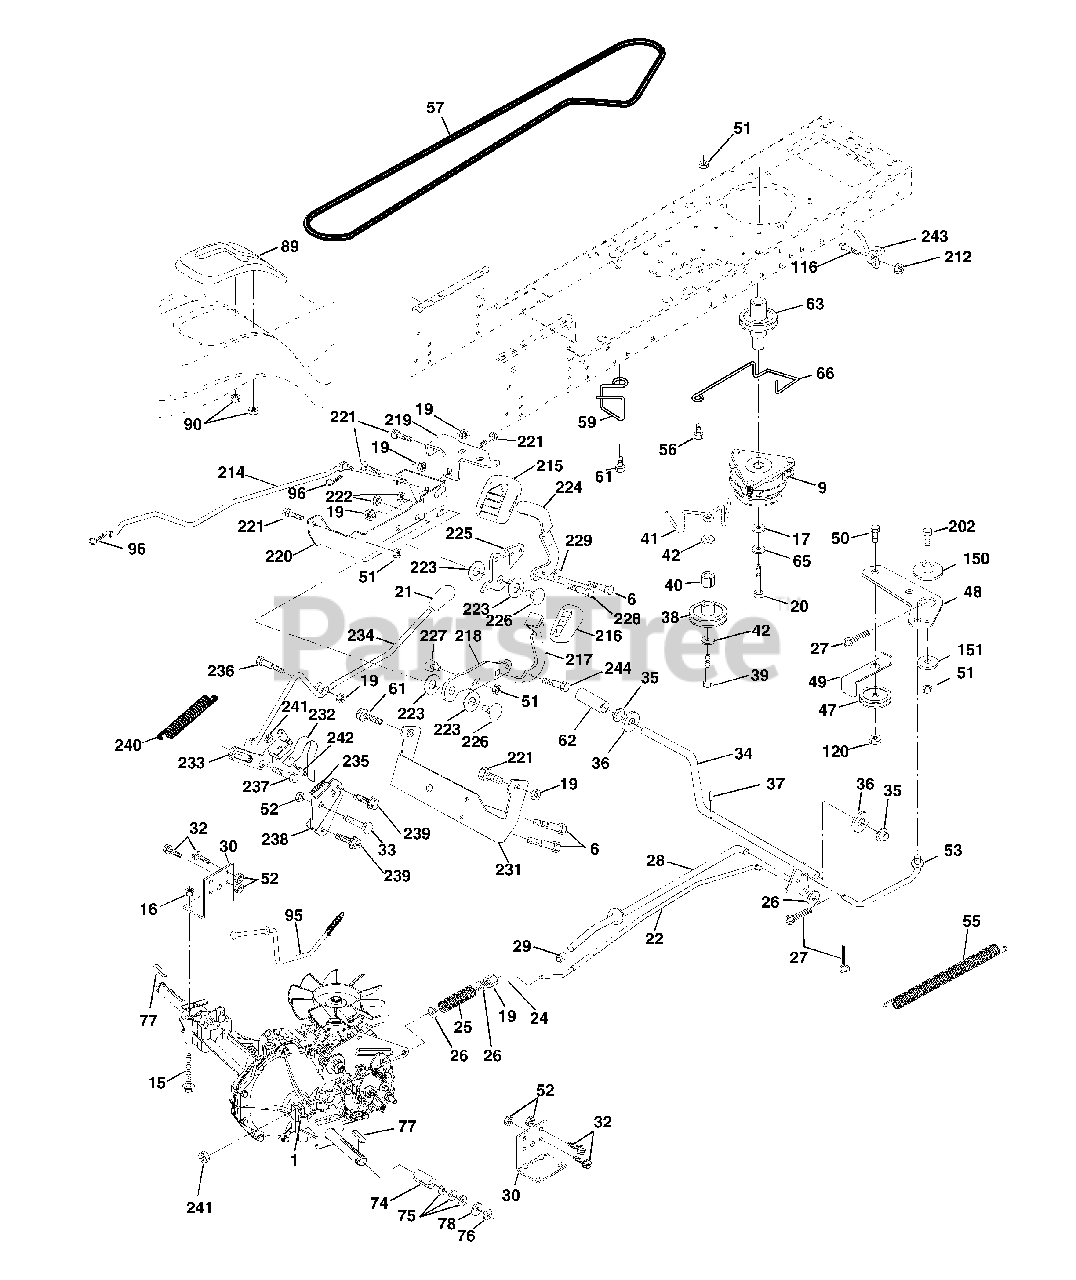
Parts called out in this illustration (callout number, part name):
1	Transaxle
9	Clutch Elec
15	Bolt Hex Flghd 5/16-18 Gr. 5
16	Nut Lock Hex W/Ins. 5/16-18 Unc
17	Washer 1-1/2 OD x 15/32 ID x .250
19	Nut Lock Hex W/Wsh 3/8-16 Unc
20	Bolt Hex 7/16-20 x 4 x Gr. 5-1.5
21	Knob Custom Control Cruise
22	Rod, Brake
24	Nut, Hex Jam 3/8-16 Unc
25	Spring, Brake Rod
26	Washer
27	Pin Cotter 1/8 x 3/4 CAD.
28	Rod, Parking Brake
29	Cap, Brake, Park
30	Bracket, Transaxle
32	Bolt Hex Hd 5/16-18 Unc x 3/4
33	Bolt Rdhd Sqnk 5/16-18 Unc x 3/4
34	Shaft, Foot Pedal
35	Bearing, Nylon
36	Washer
37	Pin, Roll
38	Pulley, Composite, Flat
39	Bolt Fin Hex 3/8-16 Unc x 3
40	Spacer, Split
41	Keeper, Belt Idler Flat
42	Washer 13/32 x 13/16 x 12 Ga.
47	Pulley, Idler, V-Groove
48	Bellcrank Clutch Grnd Drw Stl
49	Retainer, Belt
50	Bolt
51	Nut Crownlock 3/8-16 UNC
52	Nut, Crownlock 5/16-18 Unc
53	Link, Clutch
55	Spring, Return, Clutch
56	Screw 3/8-16 x 1.0
57	V-Belt, Ground Drive
59	Keeper, Center Span
61	Screw 3/8-16 x 3/4
62	Cover, Pedal
63	Pulley, Engine
65	Washer
66	Keeper Belt Engine
74	Spacer, Axle
75	Washer 25/32 x 1-1/4 x 16 Ga.
76	E-Ring
77	Key, Square
78	Washer 25/32 x 1-5/8 x 16 Ga.
89	Console, Shift
90	Nut Self-Thd Wsh-hd 1/4 Zinc
95	Rod Bypass
96	Retainer Spring 1" Zinc/Cad
116	Bolt RDHD SQNK 3/8-16 Unc x 1
120	Nut Lock Flg 3/8-16 Unc
150	Spacer Retainer
151	Washer 13/32 x 2 x 10 Ga.
202	Bolt Carr Sh 3/8-16 x 1-1/2 Gr. 5
212	Nut Hex Flange Lock
214	Link Transaxle
215	Cover Pedal Forward
216	Cover Pedal Reverse
217	Pedal Reverse
218	Arm Control Pedal Reverse
219	Bracket Frest Pdl Ctrl. Hyd
220	Bracket Mtg. Pedal Control
221	Bolt Rdhd Sqnk 3/8-16 Unc x 3/4
222	Nut Crownlock 7/16-14 Unc
223	Washer Nylon 11/16 ID x .060
224	Pedal Forward
225	Arm Control Pedal Forward
226	Bolt Pivot Spacer
227	Cam Reverse Pedal LT
228	Bolt Shoulder 5/16-18
229	Washer Serrated 5/16 x .75
230	Screw 5/16-18
231	Strap Torque
232	Actuator Cruise Disengage
233	Pawl Control Cruise
234	Lever Control Cruise
235	Sector Control Cruise
236	Bolt Shoulder 3/8-16 Unc 1/44
237	Bolt Shoulder 5/16-18
238	Arm Mtg. Cruise Sector
239	Screw Thdrol 5/16 x 1/2
240	Spring Return Cruise Control
241	Nut Centerlock 1/4-20 Unc
242	Bolt Fin Hex 1/4-20 Unc x 3/4
243	Bracket Anti-Rotation CVX
244	Screw 5/16-18 x 5/8
